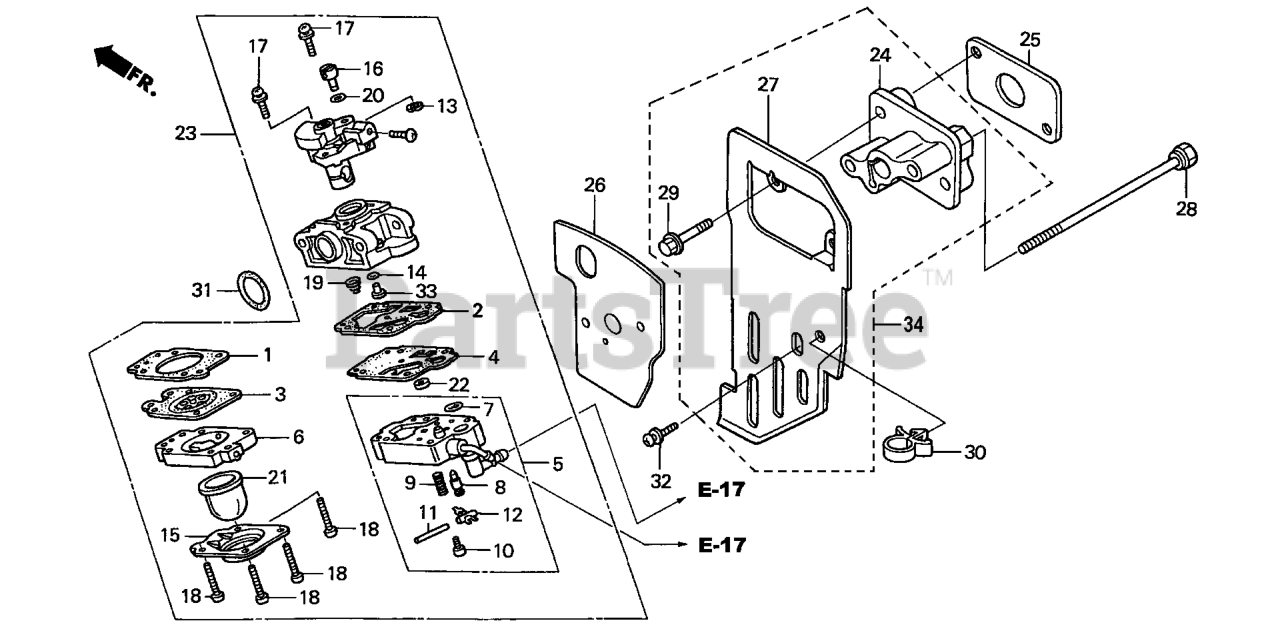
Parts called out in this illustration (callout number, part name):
1	GASKET, METERING DIAPHRAGM
2	GASKET, PUMP
3	DIAPHRAGM ASSY., METERING
4	DIAPHRAGM, PUMP
5	BODY ASSY., PUMP (CARBURETOR NO.)
6	BODY ASSY., AIR PURGE
7	SCREEN, INLET (CARBURETOR NO.)
8	VALVE, INLET NEEDLE
9	SPRING, METERING LEVER
10	SCREW, METERING LEVER PIN
11	PIN, METERING LEVER
12	LEVER, METERING
13	RING, SPRING RETAINING
15	COVER, PRIMER PUMP
17	SCREW, THROTTLE COLLAR
18	SCREW, PUMP COVER
19	SPRING, PUMP
21	PUMP, PRIMER
22	FILTER, FUEL INLET (CARBURETOR NO.)
23	CARBURETOR ASSY. (WYL 127A)
24	INSULATOR, CARBURETOR
25	GASKET, INSULATOR
26	GASKET, CARBURETOR
27	GUIDE, AIR INLET
28	BOLT, HEX. (5X75)
29	BOLT, FLANGE (5X32)
30	CLIP, WIRE HARNESS
31	O-RING (14.8X2.4)
32	SCREW-WASHER (5X10)
33	JET (#33.5) (CARBURETOR NO.) Use from Engine SN WYL127.
33	JET (#34.5) Use from Engine SN WYL127.
33	JET (#35.5) (CARBURETOR NO.)
